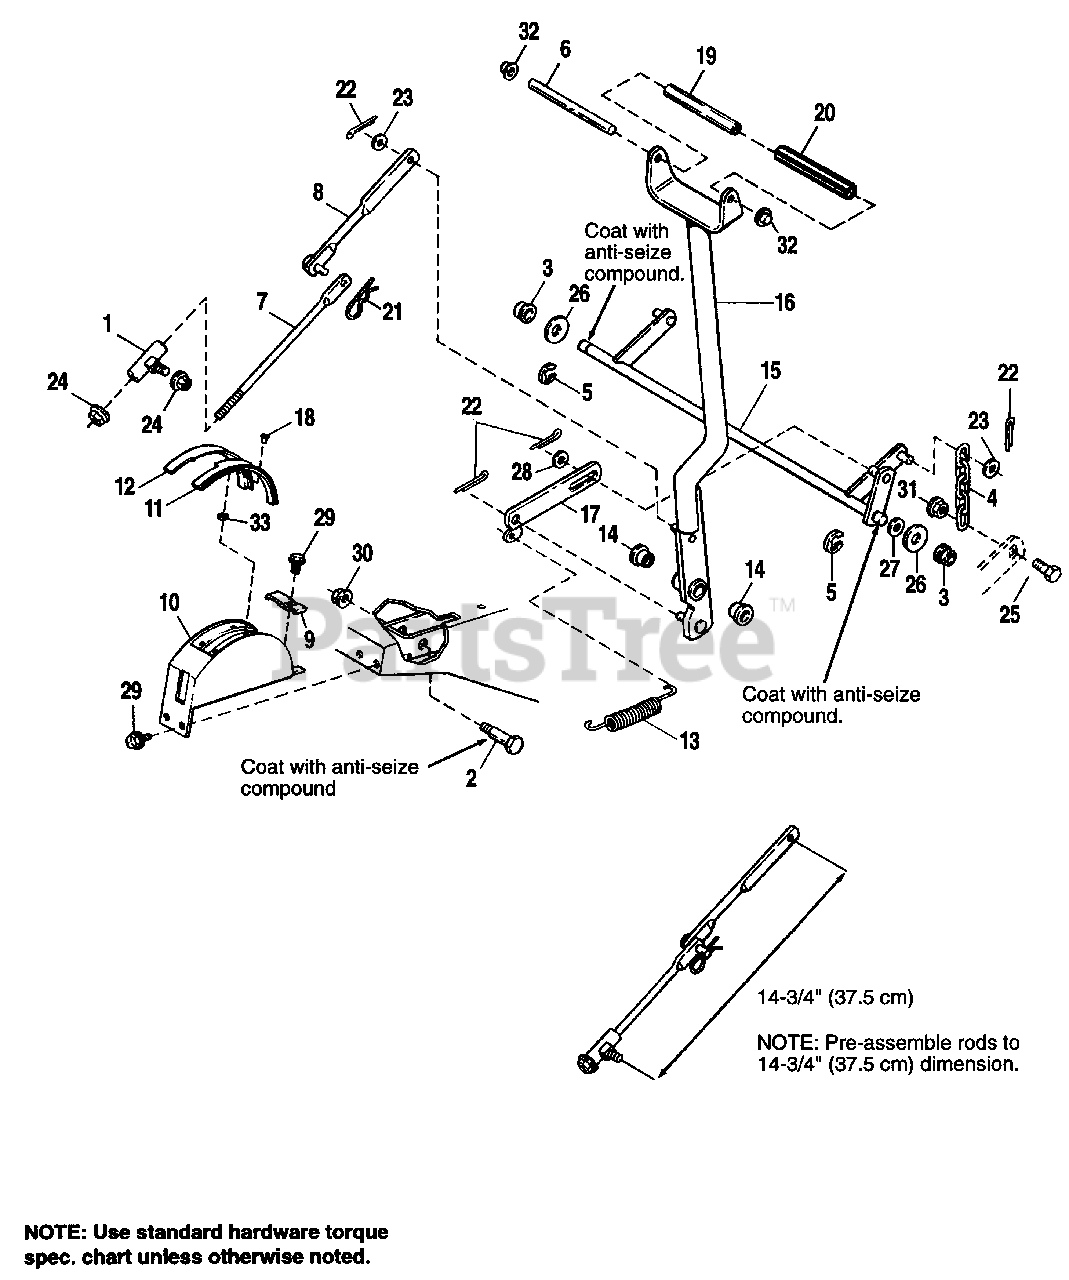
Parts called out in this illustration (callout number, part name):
1	YOKE ASSY., Pivot
2	BOLT, Shoulder
3	BUSHING, Nylon
4	CHAIN, Lift
5	KLIPRING, 1/2
7	LIFT ROD, Lower
8	LIFT ROD ASSY.
9	CLAMP, Cover
10	COVER, Lift Lever
11	STRIP, Rubber, LH
12	STRIP, Rubber, RH
14	BUSHING, Flanged
15	SHAFT ASSY., Lift
16	HANDLE ASSY., Lift
17	BAR ASSY., Lift
21	COTTER PIN, Hairpin
22	PIN, Cotter
24	NUT, Hex, ESNA Lock, 3/8-16
25	CAPSCREW, 5/16-16 x 1
26	WASHER, Plain
27	WASHER, 1/2
28	WASHER, Plain, 3/8
29	SCREW, Taptite #10-24 x 1/2
30	NUT, Whizlock, 3/8-16
31	NUT, Hex, Flange, Lock, 5/16-18
32	PUSHNUT
